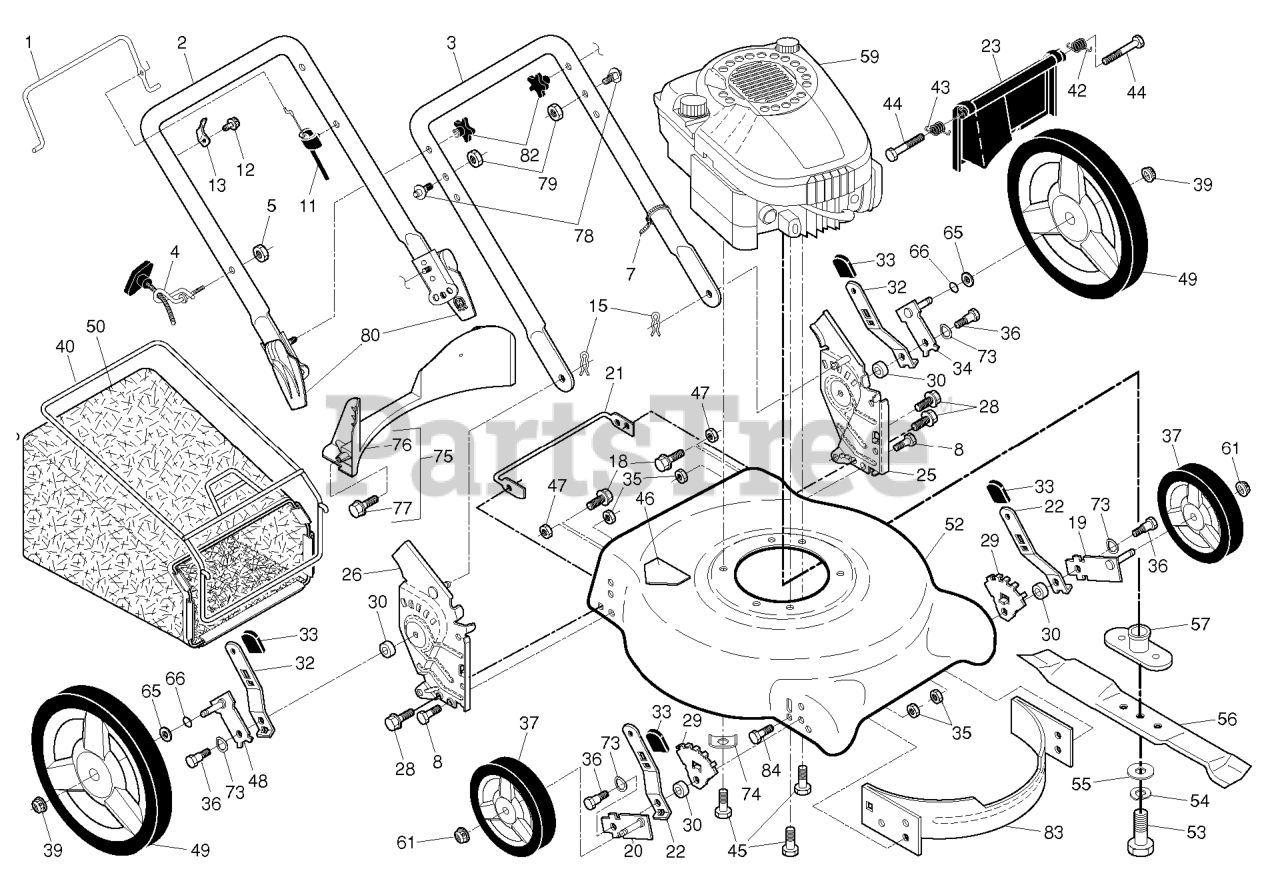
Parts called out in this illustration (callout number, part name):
1	CONTROL BAR
3	HANDLE.LOWER.ECON.PNT
4	RB GUIDE.ROPE.STD.BLK.ZIN WSL
5	NUT
7	TIE GUIDE
8	BOLT.FIN.HEX.5/16-18X3/4
11	CABLE.MZR.22.2012
13	BRACKET.UPSTOP.RT
15	HAIRPIN COTTER
18	SCREW 1/4X20
19	AXLE ARM ASSY FRONT LH
20	AXLE ARM ASSY FRONT RH
21	FOOT.GUARD.21.DOM/FGD.CE.10
22	SELECTOR SPRING, FRONT
23	DOOR.REAR.21.DOMED.498
25	BRACKET.ASM.HAND.HW.21.LT.GREY
26	BRACKET.ASM.HAND.HW.21.RT.498
28	SCREW 14-20 X 5/8
29	WHEEL ADJ BRACKET FRONT
30	SPACER.HEIGHT.ADJUSTER
32	SPRING.SEL.22.ECON.HI-WHL.RATO
33	SELECTOR KNOB
34	AXLE ARM ASSY REAR LH
35	NUT.FLANGE.HEX.5/16X18.BLACK
36	SHOULDER BOLT 5/16-18
37	WHEEL AND TIRE ASSY, REAR
39	NUT.HEX.FLANGE.3/8-16.LOCKNUT
40	FRAME.BAG.21.REAR.DOMED.PUSH
42	SPRING.LH.22.REAR.DOOR.EZ.EMPT
43	SPRING.RH.22.REAR.DOOR.EZ.
45	BOLT 3/8-16X1-1/8
46	DECAL.INTERNATIONL.CUTFINGER
48	AXLE ARM ASSY REAR RH
49	WHEEL.12X1.75H.3.SPOKE.RADIAL
50	GBAG.24710090.GENERIC H-GRY498
52	KIT.HSG.21RD.DOME.ORG.CE
53	SCREW, HEX HD 3/8-24 X 1-3/8
54	LOCKWASHER
55	WASHER,HARDEN
56	BLADE.21.PUSH
57	ADAPTER.BLADE.W/KEY.25MM.CE
61	NUT.HEX.FLANGE.3/8-16.LO(3 2)
65	WASHER.FLAT.1/2
66	O-RING..070X.487.NEOPRENE
73	WASHER.CURVED.CYLINDRICAL
74	WASHER.ENGINE.BZP
75	KIT.BAFFLE.REAR.PLASTIC.21.RD
76	BAFFLE.REAR.PLASTIC.21.RD.ECON
77	SCREW.HX.13X.750
78	STUD.QUICK.ADJUST
79	NUT.LOCK.5/16-18
80	QUICK.ASM.RELEASE.BLACK
82	KNOB.HANDLE.PLASTIC.STAR.BLACK
83	BAFFLE.FRONT.21.DOME.US
84	BOLT.5/16HEX.WHS.HD
